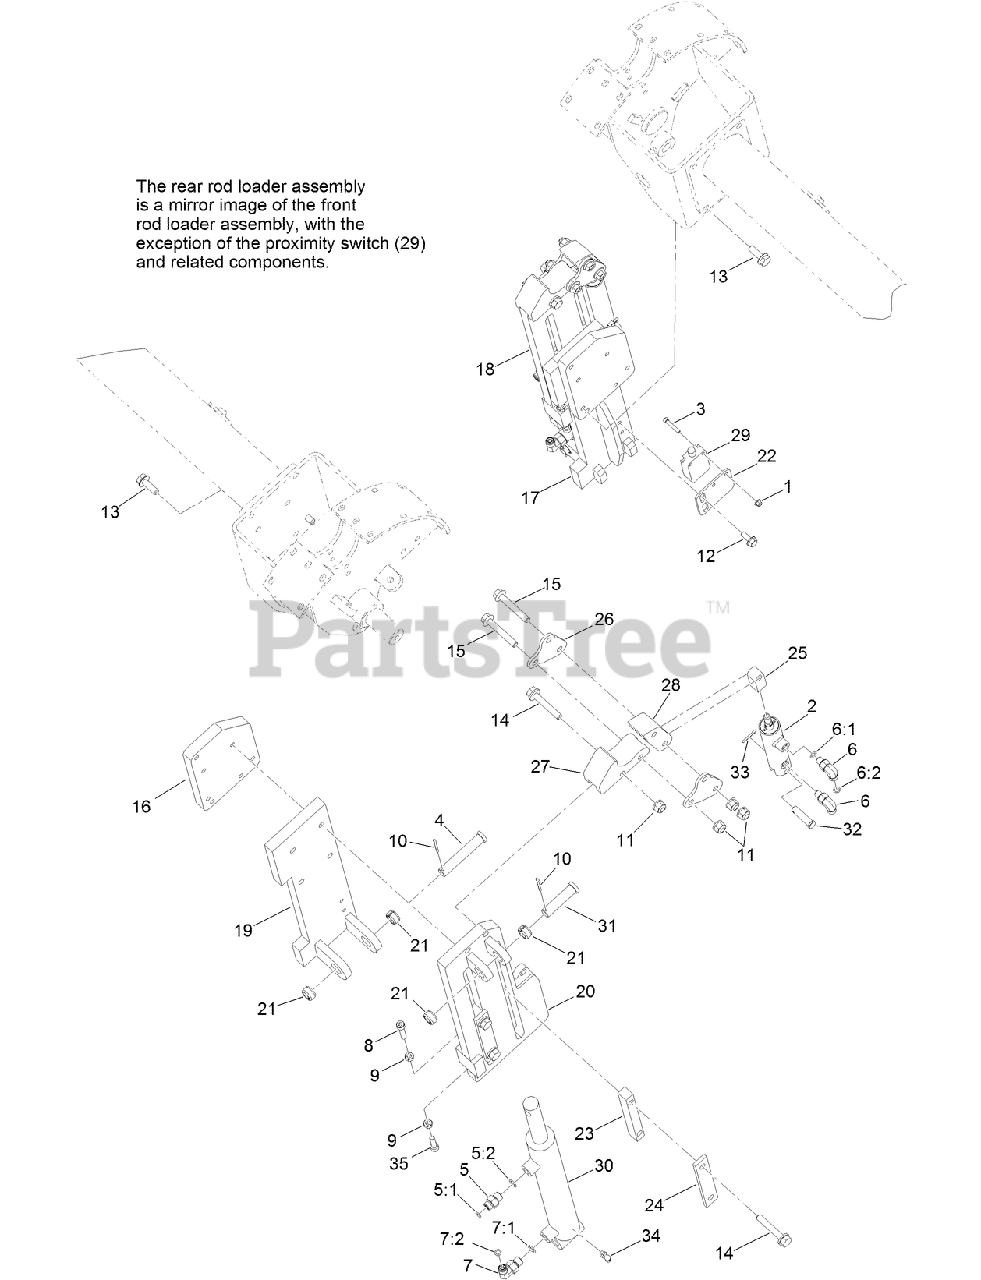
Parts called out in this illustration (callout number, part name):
1	NUT-HF
2	HYD CYLINDER ASM
3	SCREW-HSH
4	PIN-CLEVIS
5	FITTING-STRAIGHT
5:1	O-RING
5:2	O-RING
6	FITTING-90 DEG
6:1	O-RING
6:2	O-RING
7	FITTING-ELBOW 90
7:1	O-RING
7:2	O-RING
8	SCREW-HSH
9	NUT-HEX
10	PIN-COTTER
11	NUT-LOCK, NI
12	SCREW-HHF
13	SCREW-HHF
14	SCREW-HHF
15	SCREW-HHF
16	PLATE-SPACER
17	ARM-EXTENSION
18	EXTENSION-SLIDER, REAR
19	ARM-EXTENSION
20	EXTENSION-SLIDER, FRONT
21	BUSHING-SPRING
22	BRACKET-SENSOR, EXTENSION ARM
23	GUIDE-EXTENSION ARM
24	CAP-GUIDE, EXTENSION ARM
25	ROD-EYE, CYLINDER
26	PLATE-GRIPPER, ROTATE
27	INSERT-GRIPPER, FIXED
28	INSERT-GRIPPER, ROTATE
29	SWITCH-PROXIMITY
30	HYD CYLINDER ASM
31	PIN-CLEVIS
32	PIN-CLEVIS
33	PIN-COTTER
34	FITTING-GREASE, 90 DEG
35	SCREW-HSH
